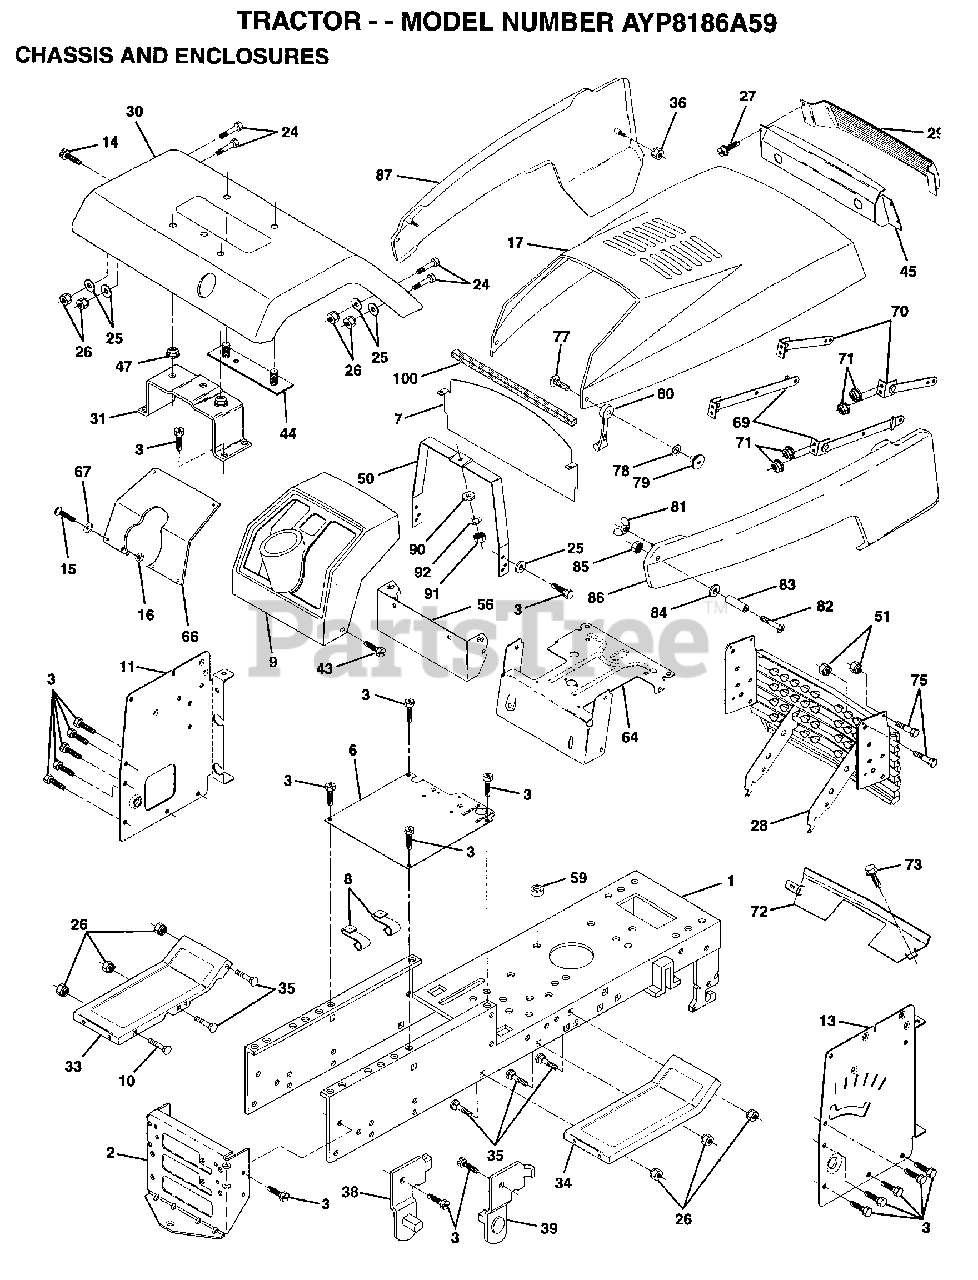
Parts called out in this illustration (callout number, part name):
1	CHASSIS.WLD.11GA
2	DRAW BAR
3	SCREW
7	"BAFFLE,HOOD"
8	"CLIP,INSULATOR"
9	DASHBOARD BLACK
11	PANEL.DASH.LH.PNT
13	PANEL.DASH.RH.PNT
14	SCREW LT
15	SCREW
24	BOLT
25	WASHER
26	NUT
29	LENS.BAR.CLEAR
30	FENDER.PNT.
31	BRKT.ASM.FENDER
33	FOOTREST.LH.LT/GT
34	FOOTREST.RH.LT/GT
35	BOLT
36	PAL NUT LT
38	BRACKET ASM LH
39	BRACKET ASM RH
43	SCREW GTV
44	STRAP ASM FENDER
47	NUT-PUSH YT
50	DASH.SUPT.YP/HUSQ
51	NUT
56	DASH.EXT.PNT.
66	PLATE DASH SILKSC
67	WASHER
71	NUT
73	SCREW CRT
77	SCREW
78	LOCKWASHER
79	WELDNUT
80	HOOD LATCH T
82	SCREW
83	SPACER LT
84	WASHER
90	WASHER PM
92	LOCKWASHER
100	FOAM-STRIP LT
